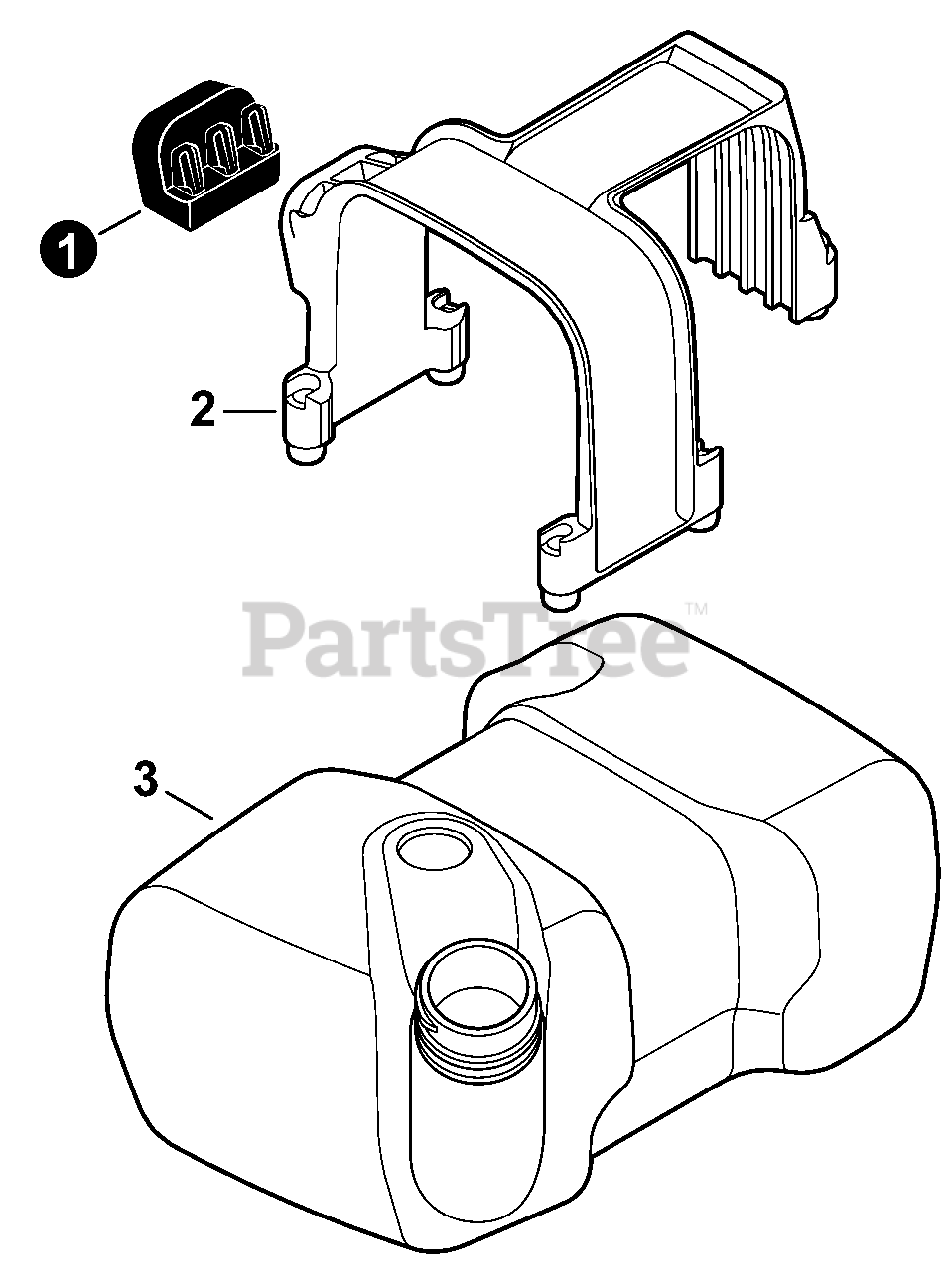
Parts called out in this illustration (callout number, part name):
1	CUSHION
2	RETAINER, FUEL TANK
3	TANK, FUEL
